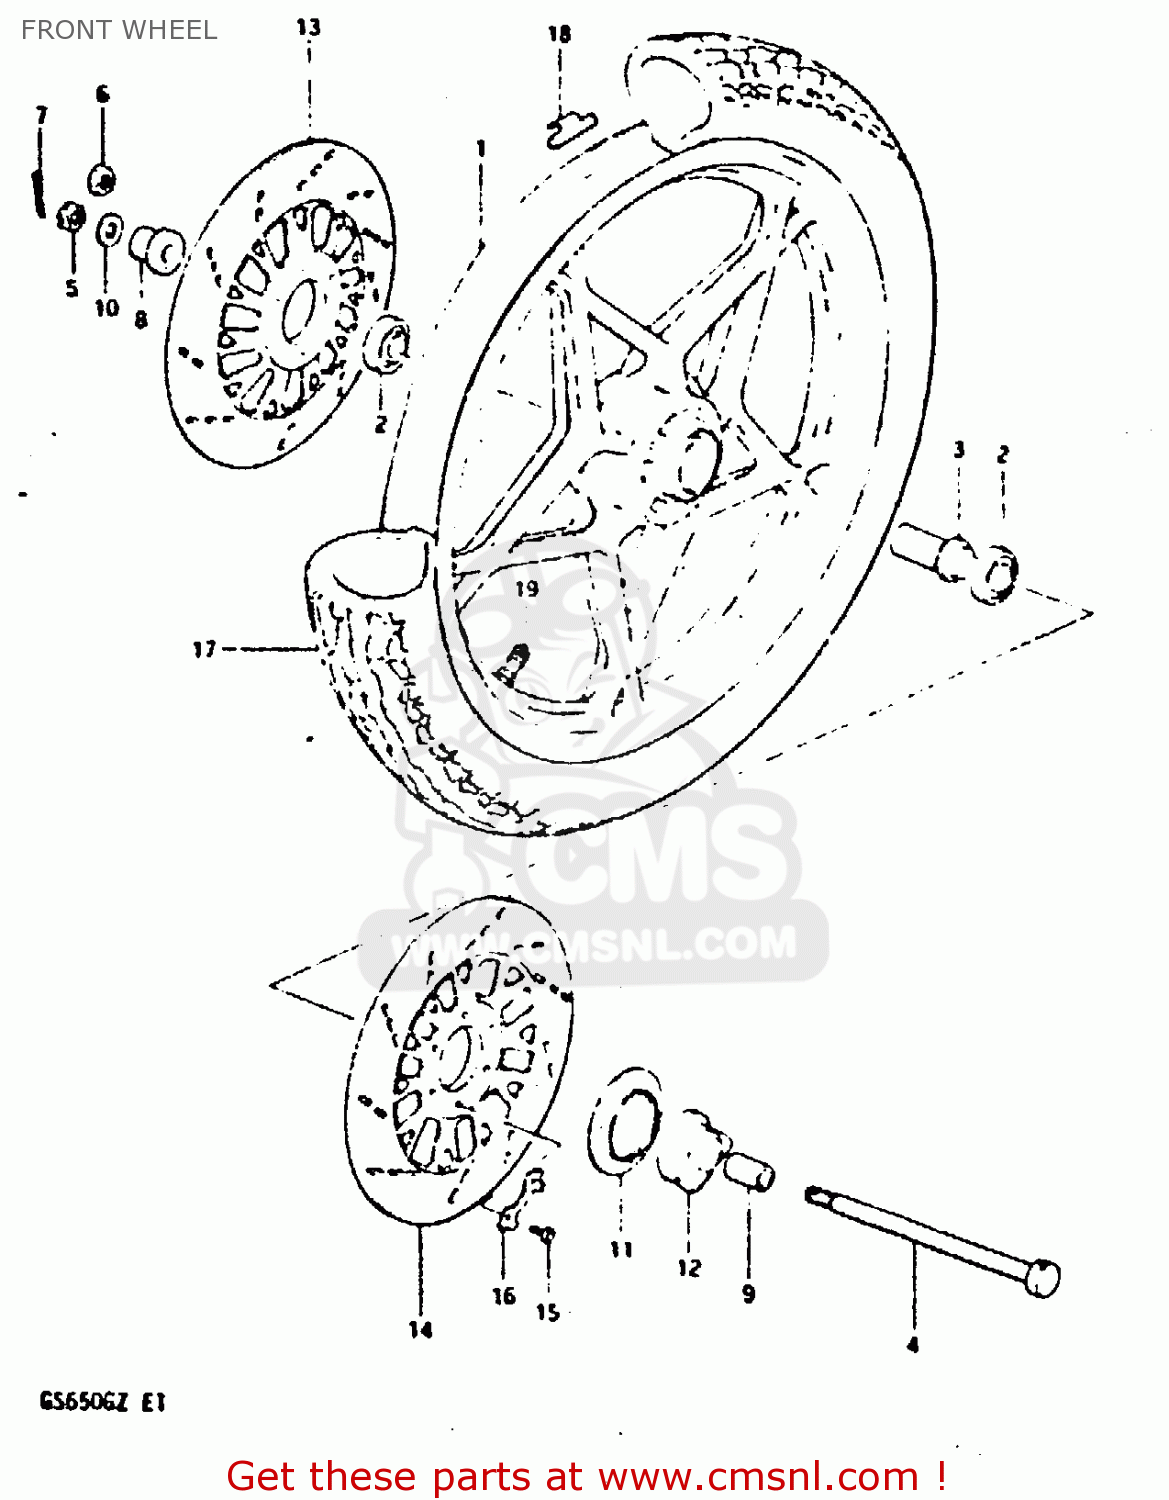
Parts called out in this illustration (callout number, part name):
1	WHEEL, FRONT (1.85-19)
2	BEARING
3	SPACER,FR HUB BEARING
4	AXLE,FRONT
5	NUT 12MM
7	COTTER PIN
8	SPACER,FR HUB BEARING,R
9	SPACER(15X22X30)
10	WASHER
11	DUST SEAL,SPEEDOMETER GEAR BOX
12	BOX ASSEMBLY,SPEEDOMETER GEAR
13	DISC,BRAKE
14	DISC,BRAKE
15	BOLT(8X28)
16	WASHER
17	TIRE,FRONT
18	BALANCER,WHEEL
19	VALVE ASSEMBLY,WHEEL RIM,J
